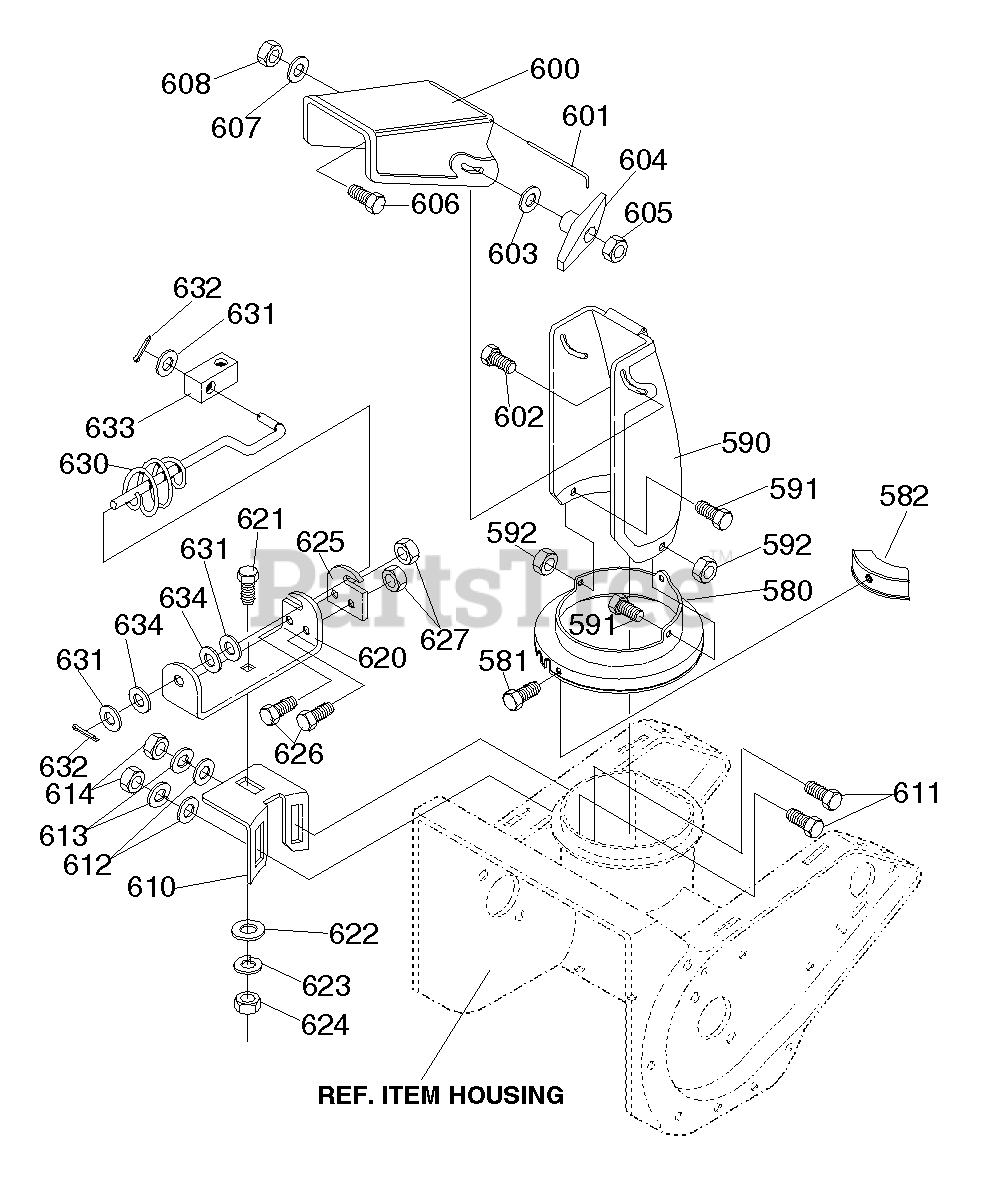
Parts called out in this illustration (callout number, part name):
580	LOWER CHUTE RING
581	SCREW 1/4-14 X.63
582	CLIP, CHUTE RING
590	LOWER CHUTE
591	SCREW, 1/4-20X.50
592	NUT, 1/4-20 MAC-LOCK
600	UPPER CHUTE
601	WIRE, HINGE
602	CARR. BOLT 5/16-18 X1.25
603	FLATWASHER
604	KNOB, T 2BLADE
605	NUT, 5/16-18 REGHEX
606	SCREW 5/16-18 X.75
607	FLATWASHER
608	NUT, 5/16-18 RGHXCTRLK
610	BRACKET, WORM ADJUST
611	CARR. BOLT 5/16-18 X.75
612	FLATWASHER
613	WASHER, HVSPTLK
614	NUT, 5/16-18 REGHEX
620	BRACKET, CHUTE ROD
621	CARR. BOLT 5/16-18 X.75
622	FLATWASHER
623	WASHER, HVSPTLK
624	NUT, 5/16-18 REGHEX
625	PLATE, CHUTE ROD
626	SCREW 1/4-20 X.50
627	NUT, 1/4-20 RGHXCTRLK
630	ROD, ASSY CHUTE CTRL
631	FLATWASHER
632	COTTER PIN
633	BLOCK, PIVOT
634	WASHER CURVED SPRING
